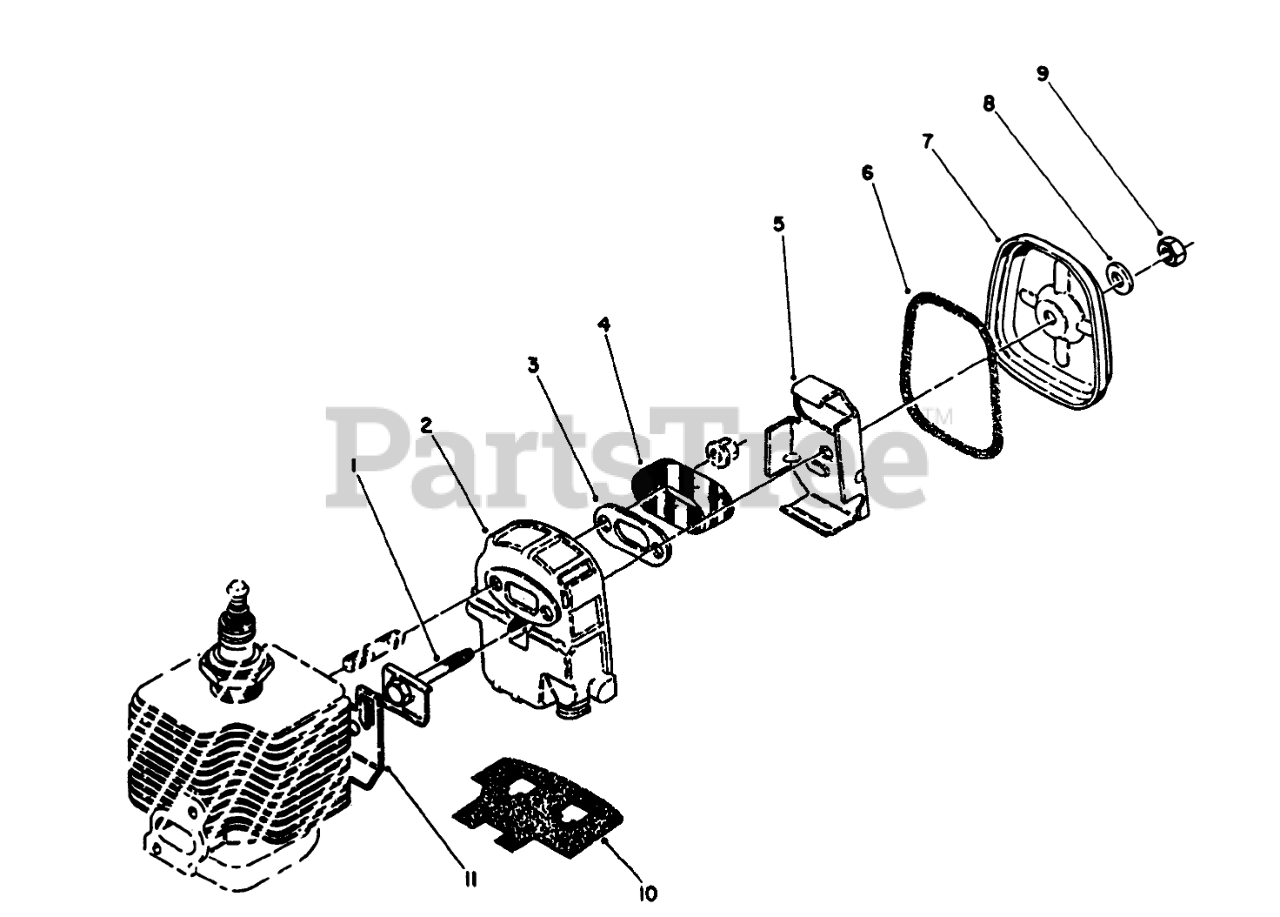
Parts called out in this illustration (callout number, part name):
2	Body-Muffler
3	PLATE
4	SCREEN
5	Plate
6	GASKET
7	MUFFLER LID
8	GASKET
10	GASKET
11	GASKET
